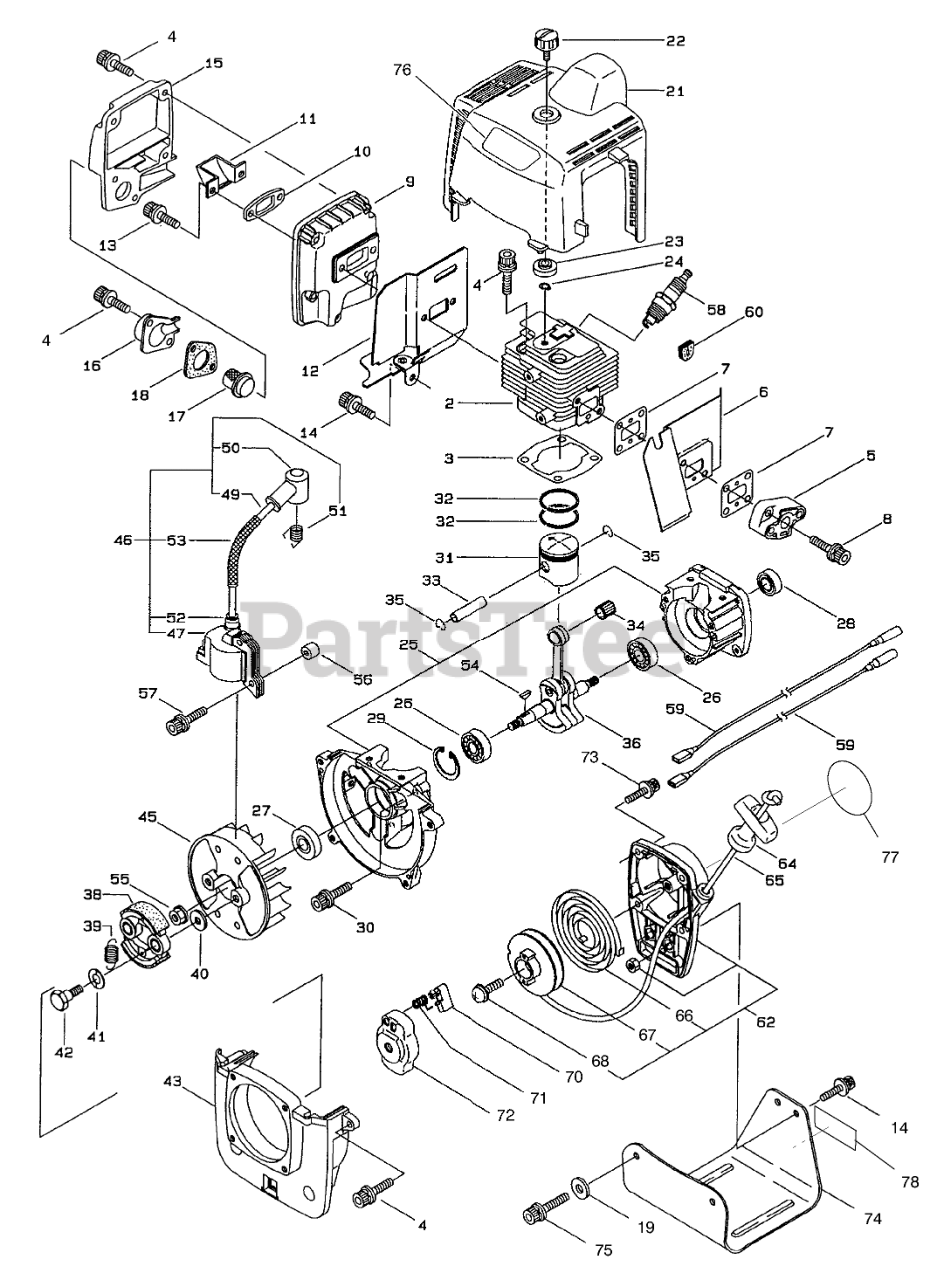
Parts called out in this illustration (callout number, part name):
2	CYLINDER
3	GASKET
5	INSULATOR
6	DUCT - AIR
7	GASKET
8	SCREW
9	BODY - MUFFLER
10	SHIELD
11	PLATE
12	GASKET
13	CAPSCREW
15	COVER - MUFFLER
16	COVER - SPARK ARRESTER
17	ARRESTER - SPARK
18	GASKET - SPARK ARRESTER
19	WASHER
21	COVER - TOP
23	SPACER
25	CRANKCASE
26	BEARING
27	SEAL - OIL
28	SEAL - OIL
29	RING - SNAP, C-SHAPED 32
31	PISTON
32	RING - PISTON
33	PIN - PISTON
34	BEARING - NEEDLE
35	CIRCLIP
36	CRANKSHAFT
38	SHOE - CLUTCH
39	SPRING - CLUTCH
40	WASHER
41	WASHER - WAVE
42	BOLT - CLUTCH
43	COVER - FAN
45	ROTOR
46	Ignition Coil Assembly (Incl. Ref. #47-53)
49	CABLE - IGNITION
50	CAP - PLUG
51	CONNECTOR
54	KEY - WOODRUFF
55	WASHER & NUT
56	SPACER
58	SPARK PLUG
60	GROMMET
62	Recoil Assembly (Incl. Ref. #63-68)
64	GRIP - STARTER
65	ROPE - STARTER
66	SPRING - SPIRAL
68	SCREW
71	SPRING - RETURN
72	STARTER
74	STAND - ENGINE,AE320
76	DECAL - TORO
77	DECAL - TORO
78	REPLACEMNT SERIAL PLT
